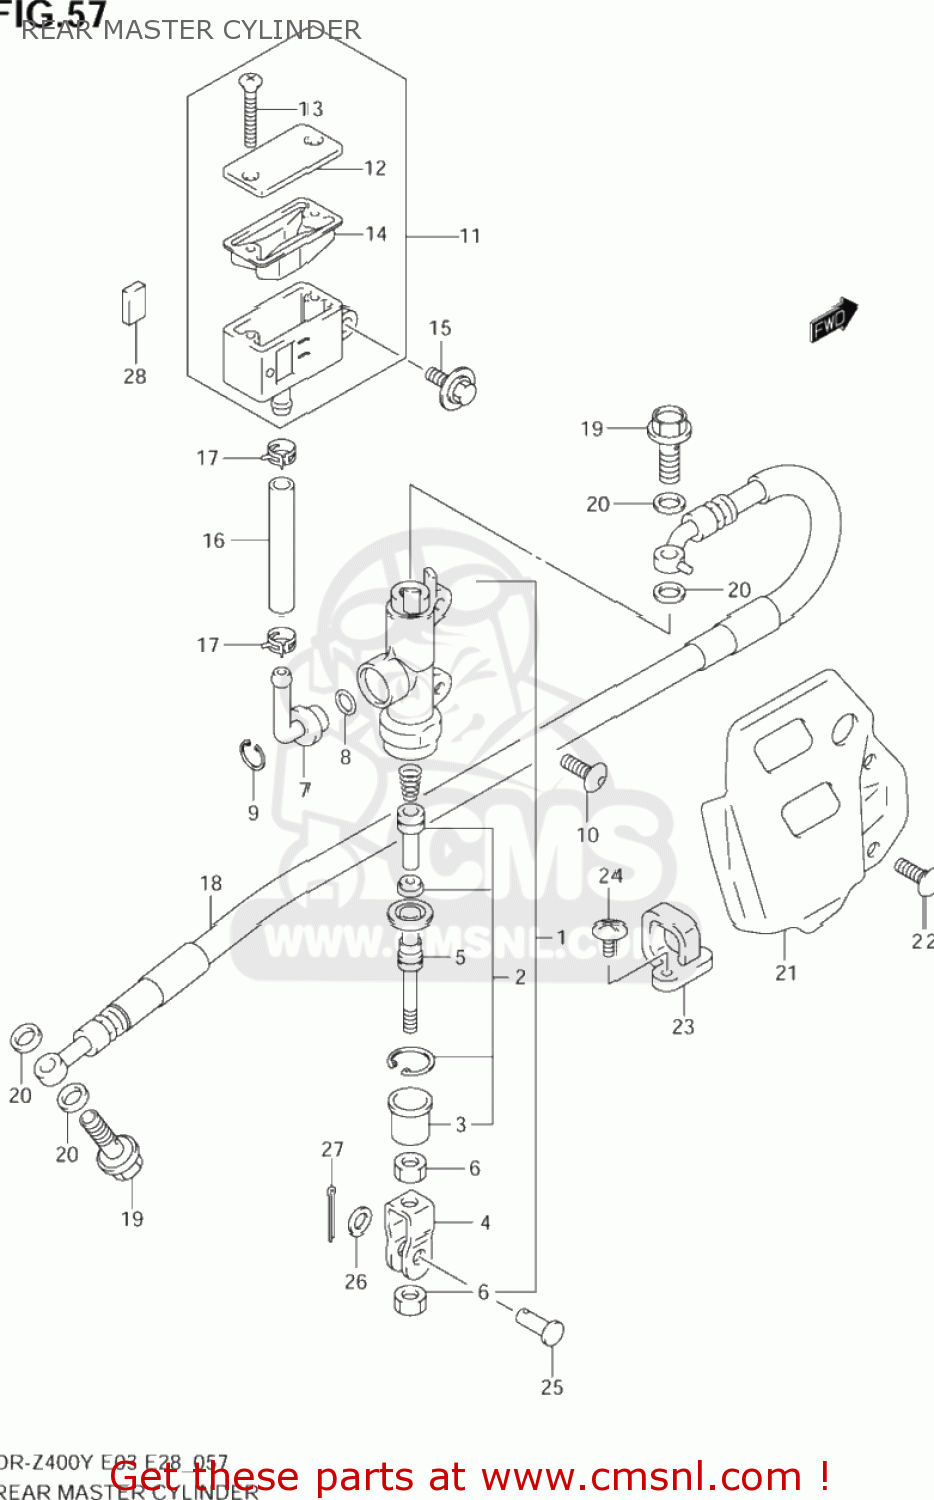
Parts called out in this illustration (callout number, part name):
1	CYLINDER ASSY,RR MASTER
2	PISTON/CUP SET
3	BOOT
4	YOKE
5	ROD,PUSH
6	NUT
7	CONNECTOR
8	O RING
9	CIRCLIP
10	SCREW(6X16)
11	TANK ASSY,RESERVOIR
12	CAP
13	SCREW
14	DIAPHRAGM
15	BOLT(6X16)
16	HOSE,FR RESERVOIR TANK
17	CLAMP,RESERVOIR HOSE
18	HOSE COMP,REAR BRAKE
19	BOLT UNION
20	WASHER(10X15X1.5)
21	GUARD,RR MASTER CYLINDER
22	SCREW(6X16)
23	GUIDE,RR BRAKE
24	SCREW
25	PIN(8X20)
26	WASHER (8.5X14X1.6)
27	PIN
28	CUSHION,RR RESERVOIR TANK
